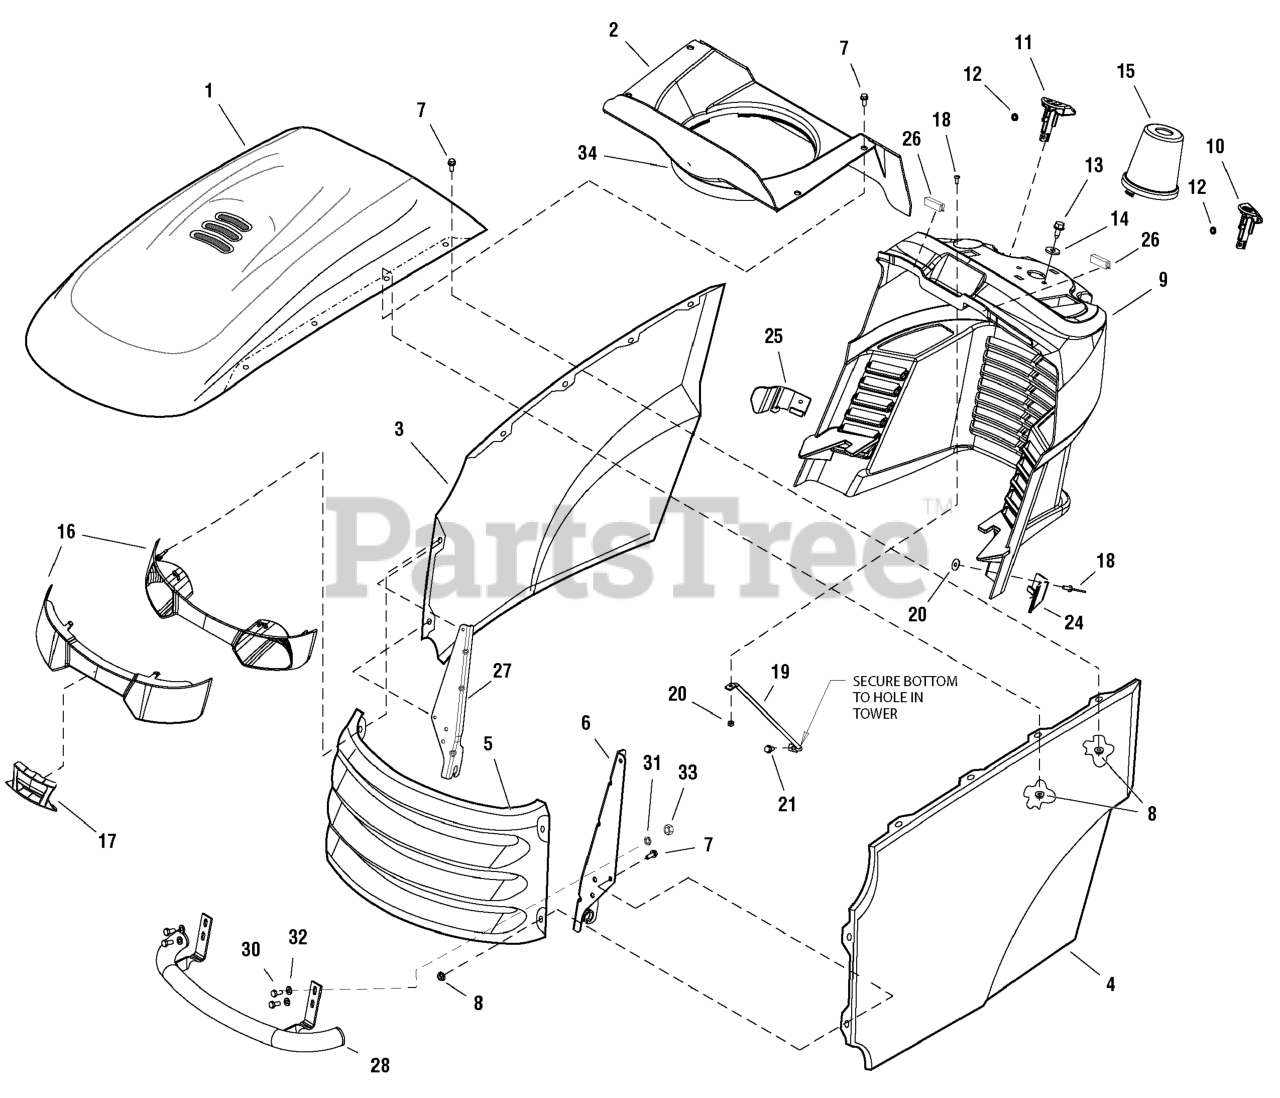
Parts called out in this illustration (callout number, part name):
1	HOOD, With Louvers
2	DUCT, Air Inlet
3	PANEL, Hood RH Side
4	PANEL,Hood LH Side
6	HINGE, Hood LH
7	CAPSCREW, Hex LK 1/4-20 x 5/8
8	NUT, Hex-Flange LK 1/4-20
9	DASHBOARD
10	KNOB, Brake Lock
11	KNOB, Cruise Lock
12	NUT, Push Pal .250
13	CAPSCREW, Hex Tapit 5/16-18 x 3/4
14	WASHER, 0.312
15	COVER, Steering Shaft
16	HEADLIGHT ASSEMBLY
17	INSERT, Light Bar
18	SCREW, Pan Head Phillips, #10-24 x 1
19	ROD, Dash Support
20	NUT, Flange
21	SCREW, Self-Tap
24	GUIDE, Hood, Left
25	GUIDE, Hood, Right
26	BRAID, Steel Insert
27	HINGE, Hood, Right
28	BUMPER, Front
30	BOLT, M8 x 20
31	WASHER, 8.4
32	WASHER, 8
34	ENDING, Rubber
